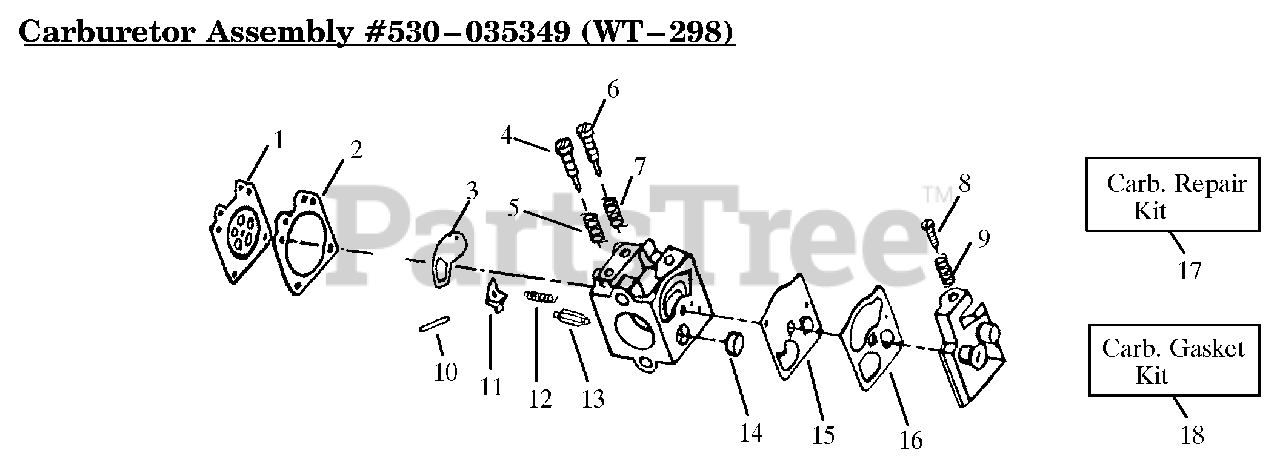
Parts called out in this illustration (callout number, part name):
1	Metering Diaphragm
2	Metering Diaphragm Gasket
3	Circuit Plate Gasket
4	Hi Speed Needle
5	Hi Speed Needle Spring
6	Idle Needle
7	Idle Needle Spring
8	Idle Speed Screw
9	Idle Speed Spring
10	Metering Lever Pin
11	Metering Lever
12	Metering Lever Spring
13	Inlet Needle Valve
14	Inlet Screen
15	Pump Diaphragm
16	Pump Gasket
17	Carb. Kwik Repair Kit
18	Carb. Gasket/Diaphragm Kit
530-035349	Carburetor Assembly - WT298
